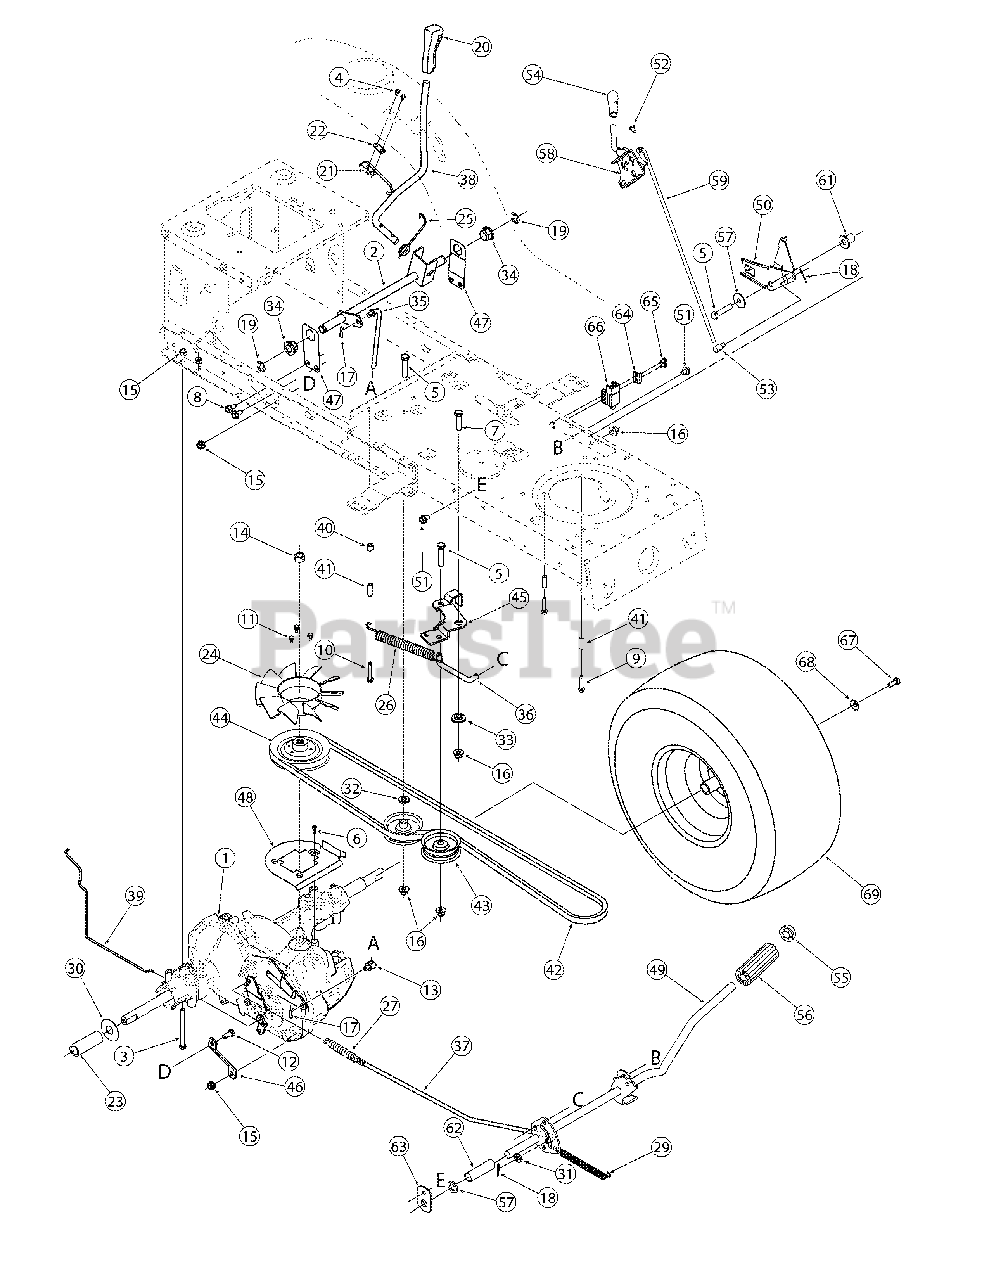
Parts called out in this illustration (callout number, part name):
1	Transmission Assembly, Hydrostatic
2	Control Assembly, Hydrostatic
3	Hex Screw, 5/16-18, 2.75, Gr5,
4	Screw, #8-18, 0.500
5	Hex Screw, 3/8-16, 1.75, Gr5
6	Screw, B, #10-16, 0.500
7	Hex Screw, 3/8-16, 1.00, Gr5
8	Screw, 5/16-12, 0.750
9	Screw, 1/4-20, 1.250
10	Screw, 1/4-20, 1.625
11	Screw, #12-24, 0.375
12	Hex Screw, 5/16-18, .75, Gr5
13	Ferrule, 5/16-18 x .312 Dia.
14	Nut, Hex Lock, 1/2-20, Gra
15	Nut, Flange Lock, 5/16-18, Grf, Nylon
16	Nut, Flange Lock, 3/8-16, Grf, Nylon
17	Pin, Cotter, .072 Dia. x 1.13
18	Pin, Cotter, 3/32, 1.0
19	Ring, E-Type, .625 Dia.
20	Grip, Handle, 1/2
21	Spring Switch, Hydro
22	Plate, Insulator Nut
23	Sleeve, .758 x .821 x 1.50
25	Spring, Torsion
26	Spring, Extension, .75 OD x 6.02
27	Spring, Extension, .59 OD x 4.00
29	Spring, Extension, .50 Dia x 6.37
30	Washer, Flat, .755 x 1.92 x .060
31	Washer, Flat, .344 x .750 x .120
32	Washer, Flat, .407x.812x.135
33	Spacer, Shoulder, .625 ID x .169
34	Bearing, Hex Flange
35	Control Rod, Hydrostatic
36	Declutching Rod
37	Brake Rod, Hydrostatic
38	Control Handle, Hydrostatic
39	Bypass Rod, Hydrostatic
40	Spacer, .254 x .50 x .390
41	Spacer, .260 x .372 x 1.030
43	Idler Pulley, Flat 2.75 OD
44	Pulley, Input, 5.0 OD
45	Idler Arm
46	Bracket, Torque
47	Mounting Bracket, Handle
49	Pedal Assembly, Drive
50	Latch Assembly, Engagement
51	Screw, 5/16-18, 0.50,
52	Screw, 1/4-14, 0.625
53	Ferrule 1/4-20
55	Push Cap, 5/8
56	Foot Pad, 4.0
57	Washer, Flat, .640 x 1.00 x .120
58	Lever, Parking Brake
61	Spacer, Flange, .390 x .671 x .95
62	Spacer, .640 x .76 x 2.63
63	Support Bracket, Pedal
64	Plate, Switch
65	Screw, #10-16, 0.500
66	Switch, Interlock
67	Screw, 5/16-24, .750, Gr5
68	Bell Washer, .34 x .872 x .060
